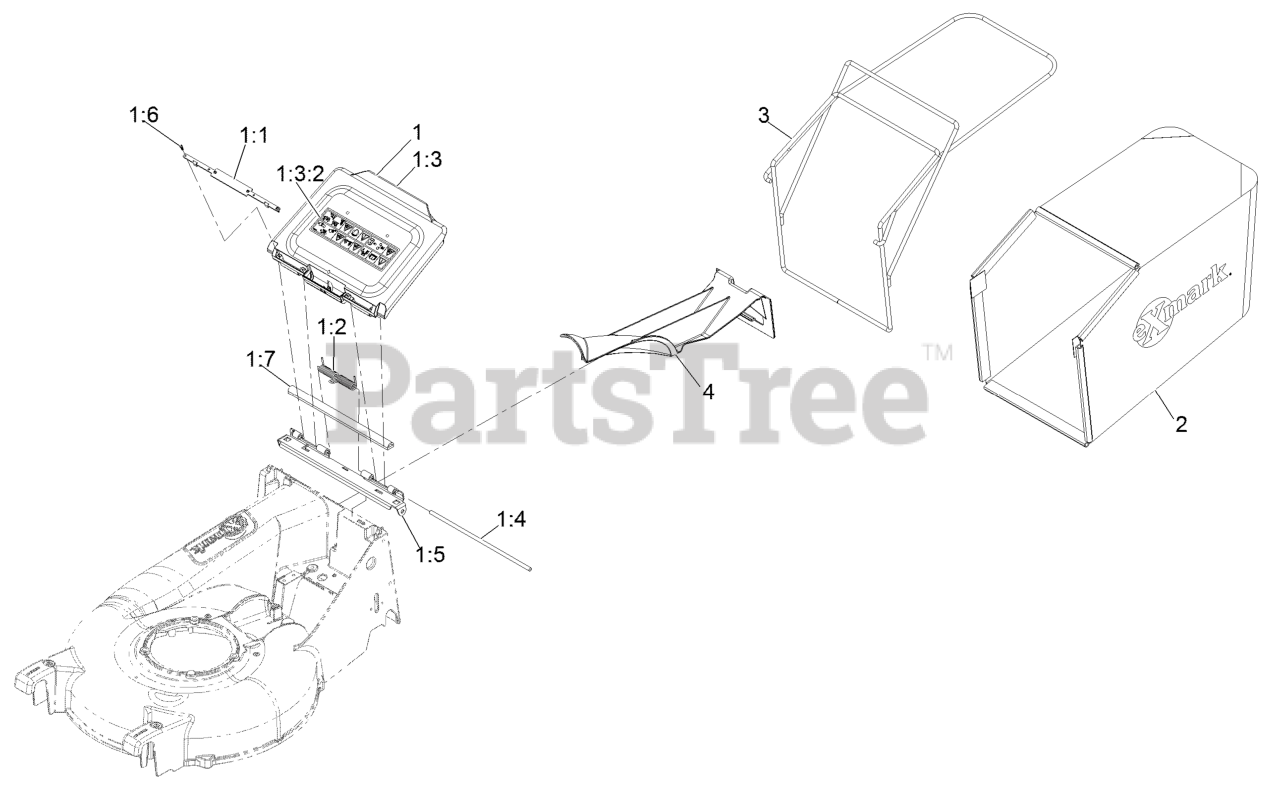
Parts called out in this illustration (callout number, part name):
1	DOOR ASM
1:1	PLATE, DOOR COVER
1:2	SPRING-PLASTIC DOOR
1:3	ASM-DOOR & DECAL
1:3:2	DECAL-WARNING
1:4	PIN-DOOR PIVOT
1:5	BRACKET-DOOR PIVOT
1:6	SCR,TAP,6-19X7/16,PHPH, S
1:7	SEAL-EPDM FOAM BULB
2	BAG-21 GRASS
3	WLD-BAG FRAME
4	PLUG,MULCH
